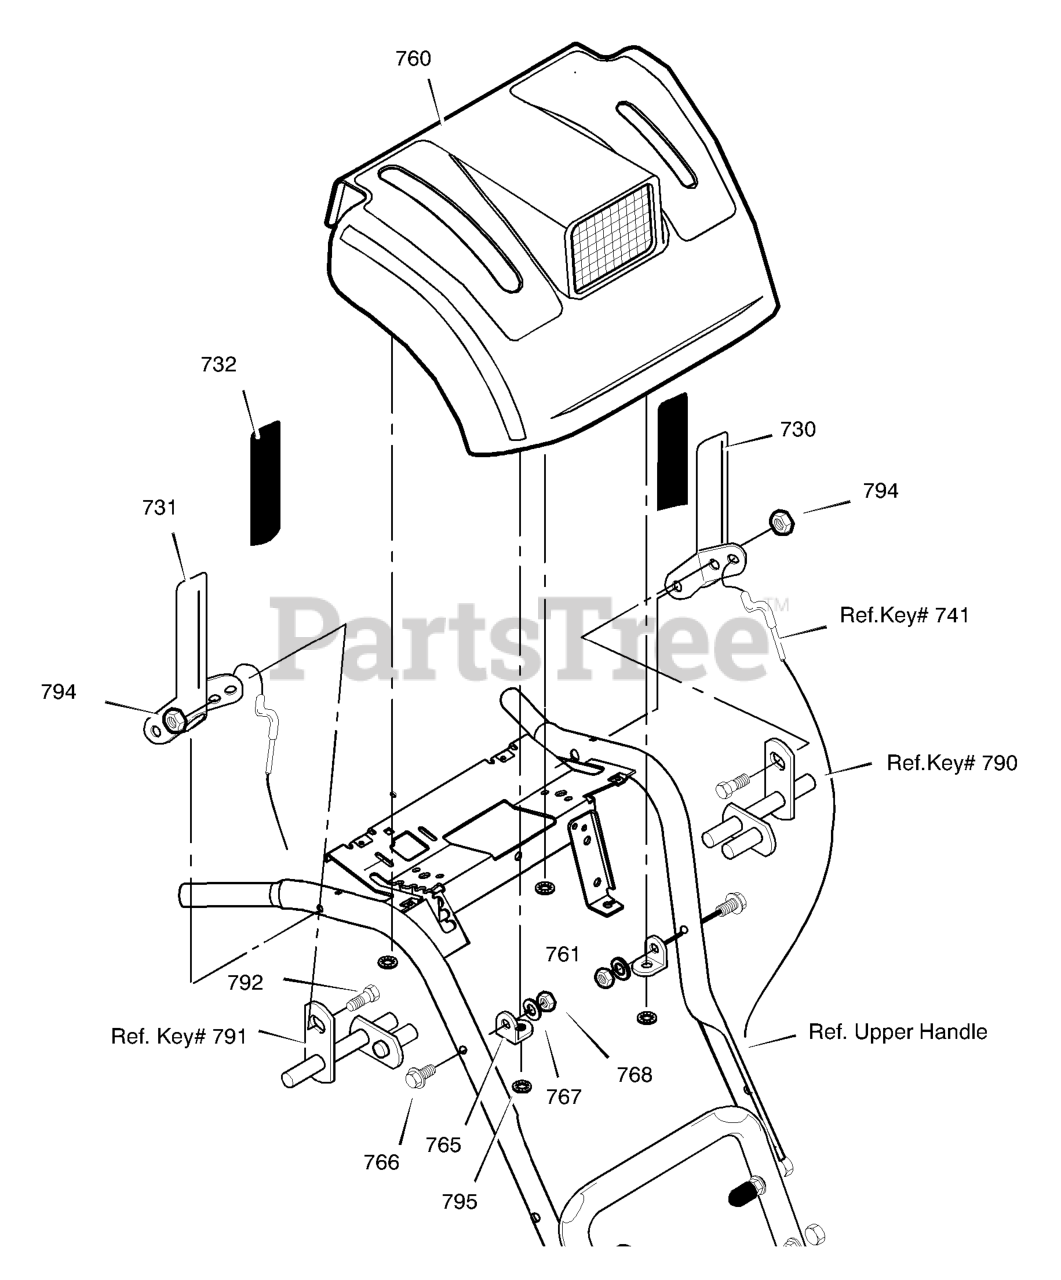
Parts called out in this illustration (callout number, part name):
730	CLUTCH HANDLE LH
731	CLUTCH HANDLE RH
732	GRIP, CLUTCH HANDLE
760	PANEL, CONTROL
765	BRACKET, PANEL
766	SCREW, 5/16-18 x 1.75
767	WASHER
768	NUT, 5/16-18
792	BOLT, 1/4-20 X .50
794	NUT, 1/4-20
795	NUT, PUSH
